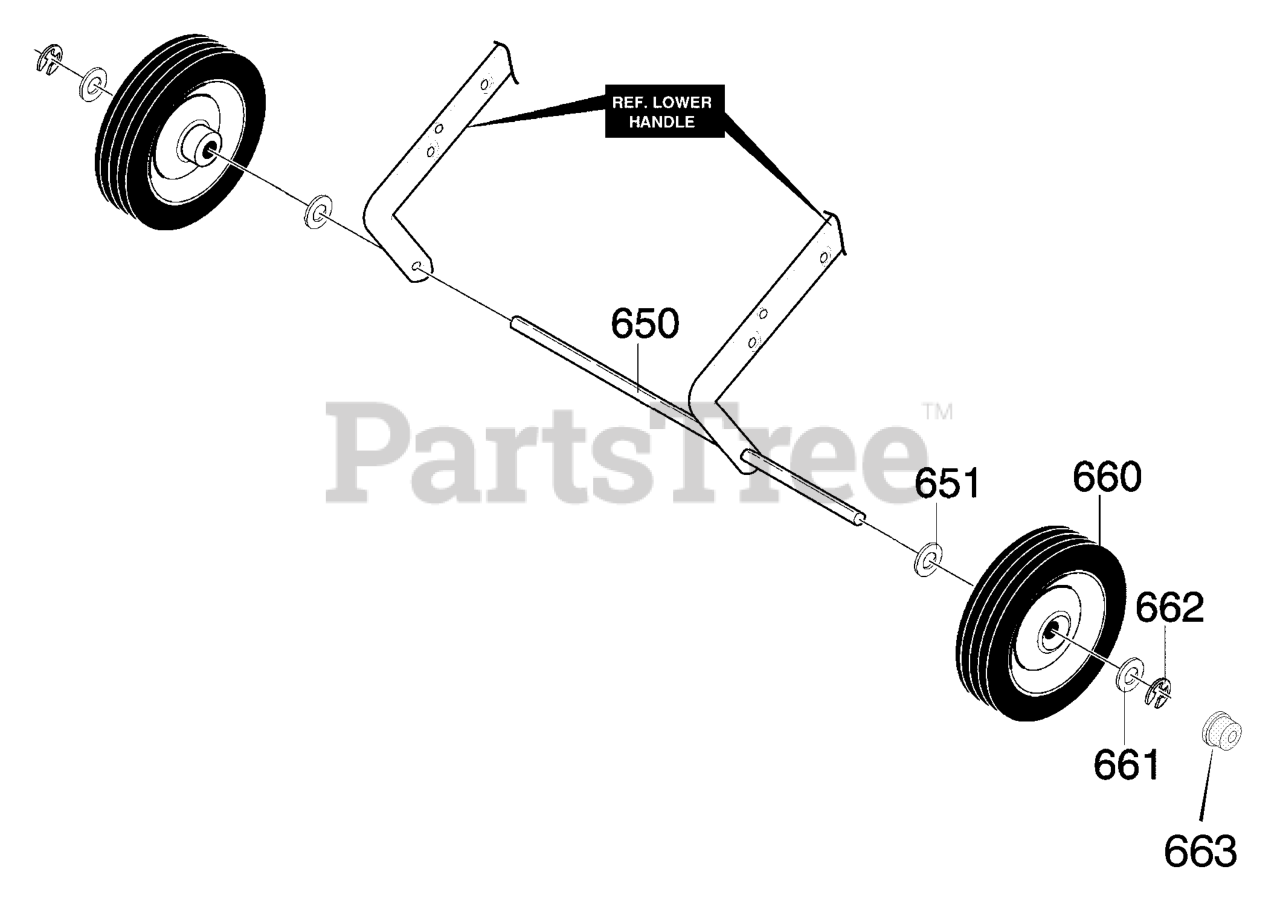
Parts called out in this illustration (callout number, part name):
650	AXLE SHAFT
651	WASHER, FLAT
660	TIRE & RIM
661	WASHER, FLAT
662	RING, RET E
663	CAP, HUB
